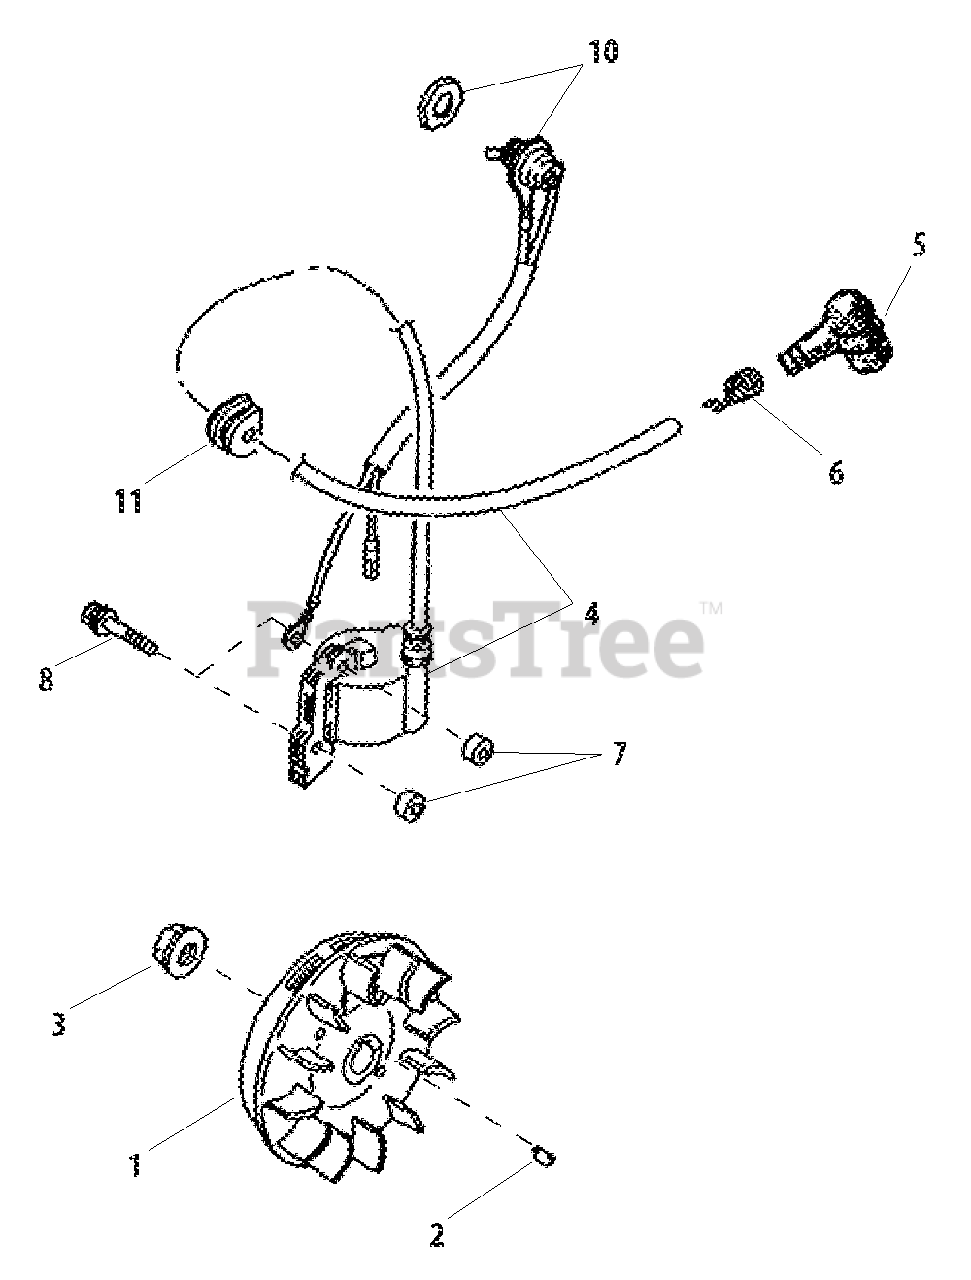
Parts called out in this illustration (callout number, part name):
1	FLYWHEEL
2	KEY, WOODRUFF 3×10
3	NUT M8
4	COIL, IGNITION
5	CAP, SPARK PLUG
6	TERMINAL, SPARK PLUG
7	INSULATOR 4.2×11×6
8	BOLT M4×26
10	SWITCH, ON-OFF
11	GROMMET
